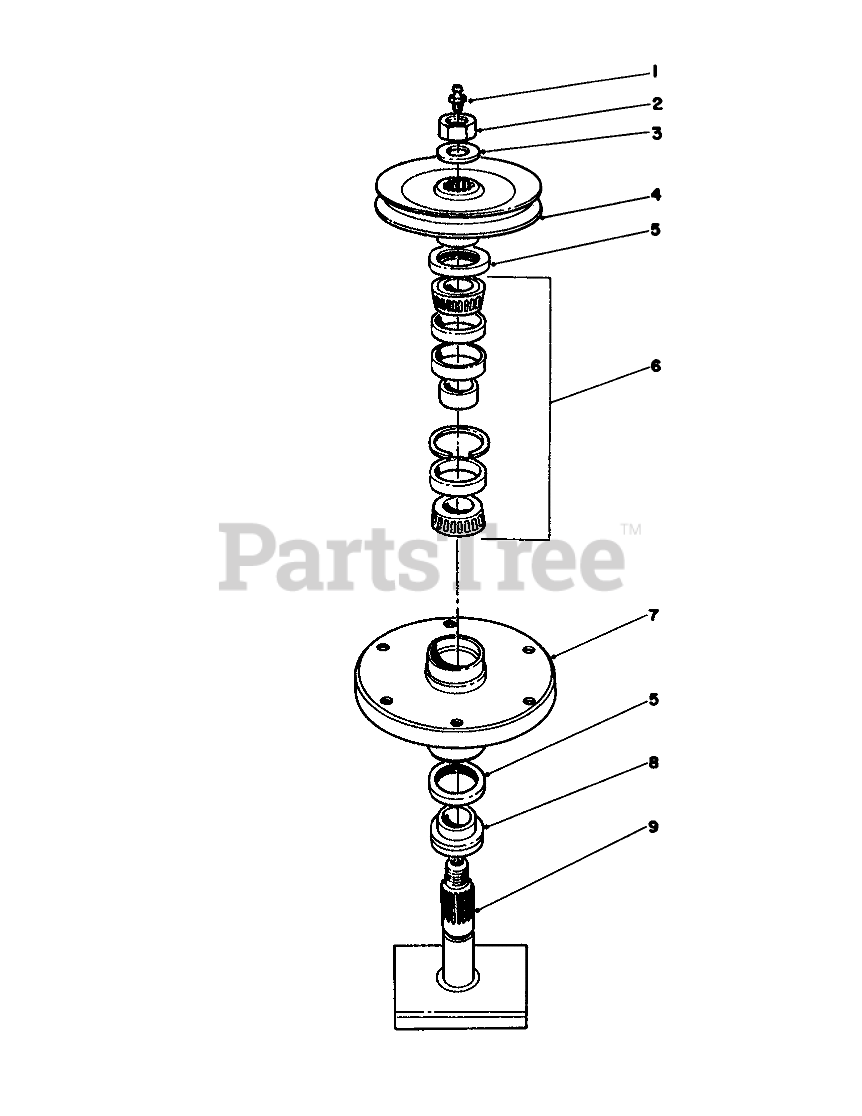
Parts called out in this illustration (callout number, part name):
1	FITTING-GREASE
2	NUT-HEX
3	WASHER
4	PULLEY AND HUB ASM
5	SEAL-OIL
6	BEARING ASM
7	HOUSING-SPINDLE
8	SPACER
9	SHAFT
